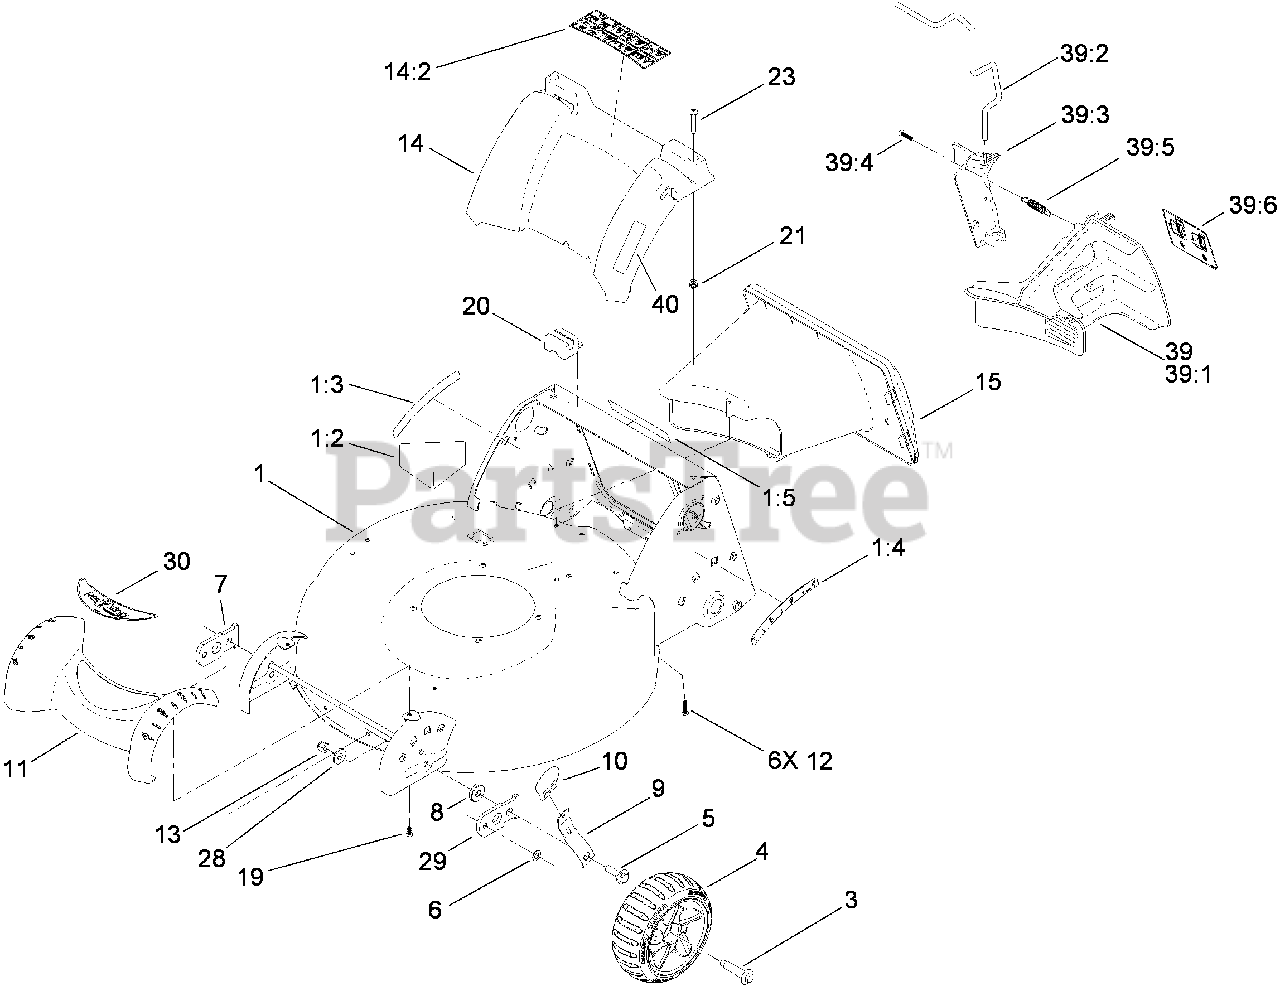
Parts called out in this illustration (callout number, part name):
1	HOUSING ASM
1:2	DECAL-DANGER
1:3	DECAL-HOC, RH
1:4	DECAL-HOC, LH
1:5	DECAL-SAFETY
3	BOLT-SHOULDER
4	7 INCH FRONT WHEEL ASM
5	BOLT-SHOULDER
7	ARM-PIVOT, RH
9	ARM-SPRING
11	COVER-FRONT
12	SCREW-PLASTITE
13	NUT-LOCK, NI
14	COVER-REAR
14:2	DECAL-WARNING
19	SCREW-PLASTITE
20	MODULE-SWITCH
21	NUT-CLIP
23	SCREW-PTH
28	WASHER-HARDENED
29	ARM-PIVOT, LH
39	MULCH PLUG ASM
39:1	PLUG-MULCH, LH
39:2	LATCH-PLUG, MULCH
39:3	PLUG-MULCH, RH
39:4	SCREW-PLASTITE
39:5	SPRING-EXTENSION
39:6	DECAL-PLUG, MULCH
40	DECAL
